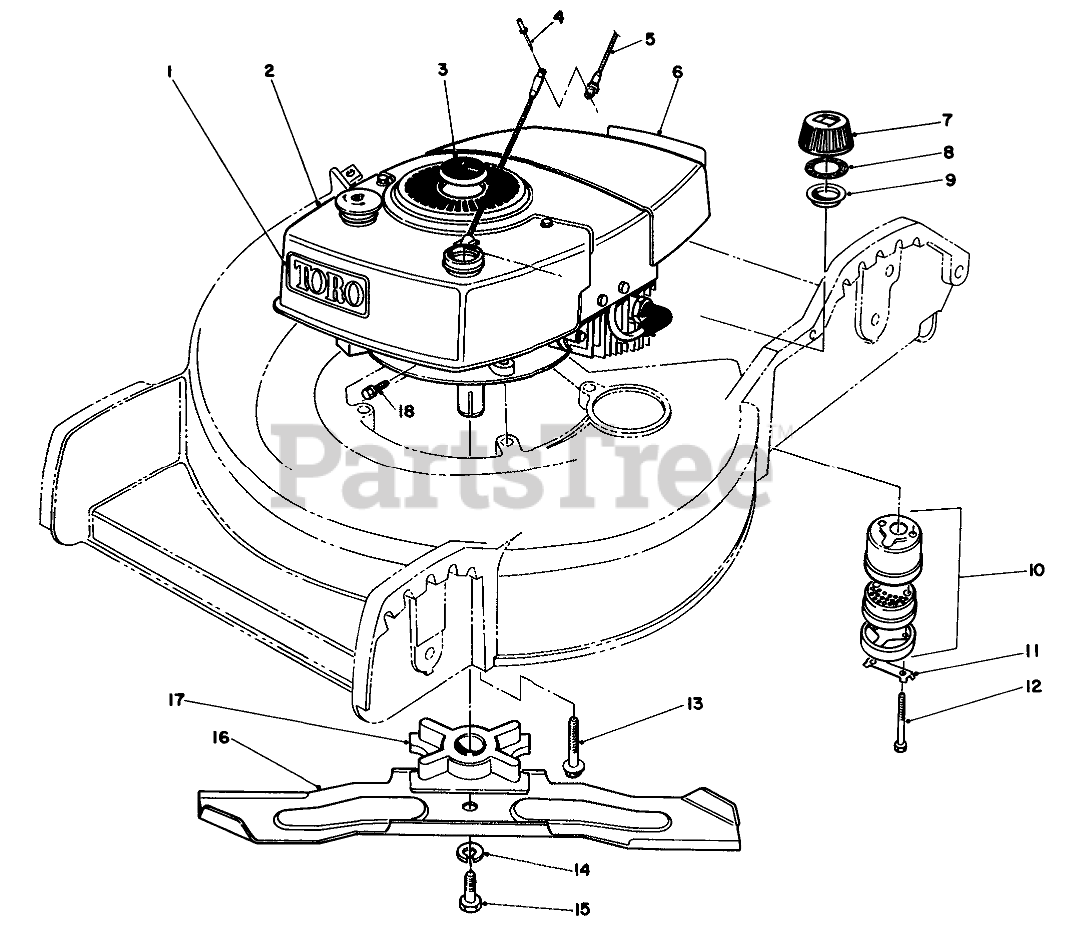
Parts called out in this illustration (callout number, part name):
1	Decal Tow
2	Engine
3	PLUG BUTTON
5	Rope-Starter
6	Decal-Maintenance
7	Gas Cap Assembly (Incl. Ref. #8 & 9)
8	GASKET
9	GAS CAP BAFFLE
10	Muffler Assembly (Incl. Ref. #11 & 12)
11	CLIP - LOCKING
12	SCREW-HH
13	3/8-16 X 2 CAPSCREW
14	WASHER-LOCK
15	SCREW-HH
16	Blade
17	BLADE RETAINER
18	SCREW-HH
